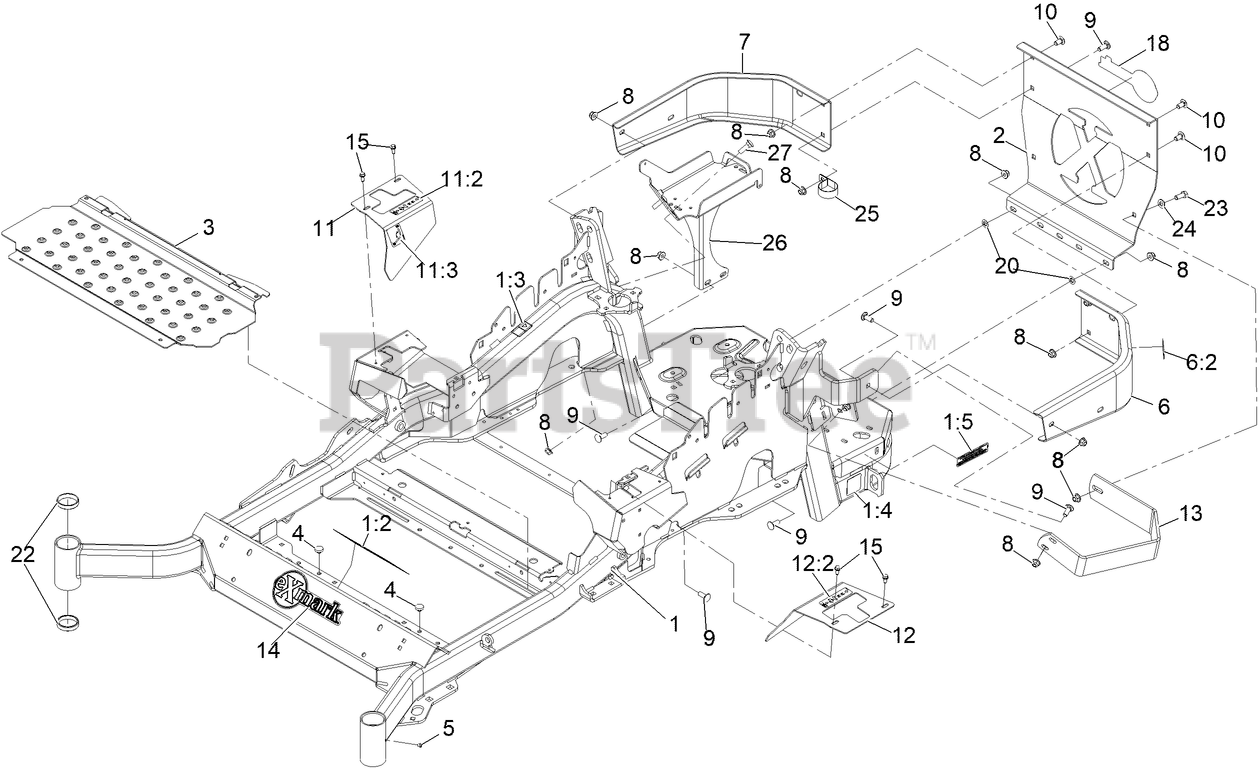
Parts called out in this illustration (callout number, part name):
1	MAINFRAME SERVICE ASM - 60
1:2	DECAL-DANGER
1:3	DECAL-WARNING
1:4	DECAL-HAZARD, PINCHED FINGER
1:5	DECAL-ARRESTOR, SPARK
2	PLATE,REAR GUARD
6	LH BUMPER ASM
6:2	DECAL-WARNING
7	BUMPER-RH
8	NUT-HF, NI
9	SCREW-CARR
10	SCREW-CARR
11	RH MOTION CONTROL COVER ASM
11:2	DECAL-CONTROL, MOTION
11:3	DECAL-PARK BRAKE, CE
12	LH MOTION CONTROL COVER ASM
12:2	DECAL-CONTROL, MOTION
13	GUARD-MUFFLER
14	DECAL-EXMARK
15	SCREW-HWH
18	DECAL, EXMARK LOGO
20	NUT-PUSH
22	CUP-BEARING
23	SCREW-HH
24	WASHER-FLAT
25	CLAMP-R
26	BATTERY MOUNT ASM
27	BOLT-CARR
